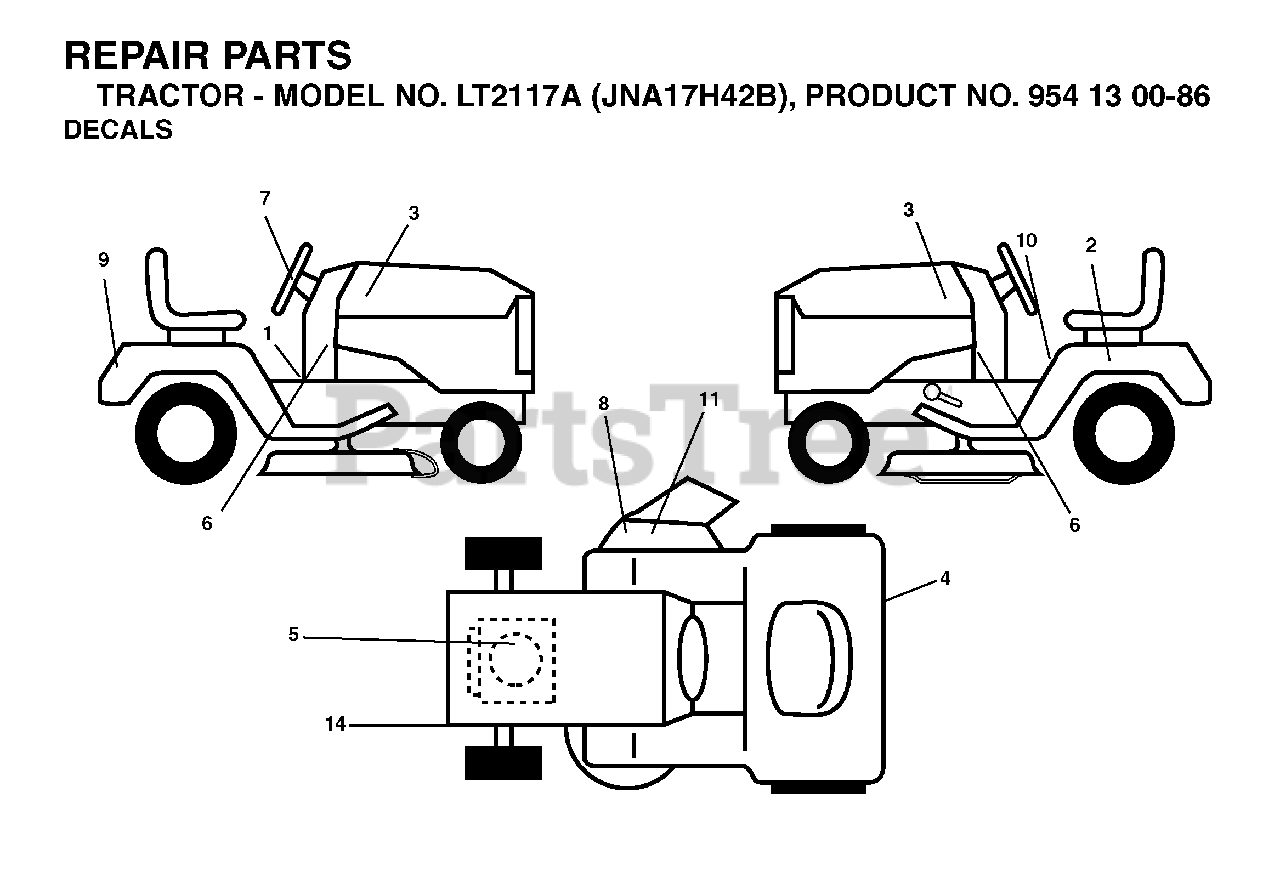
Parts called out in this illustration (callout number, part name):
1	DECAL SET
2	DECAL BTRY SYMBOLS
8	DECAL.WARN.KEEP.HAND.AWAY
10	DECAL FENDER DANGER
11	DECAL DECK "B" 42"
14	DECAL V BELT SCHEMATIC
